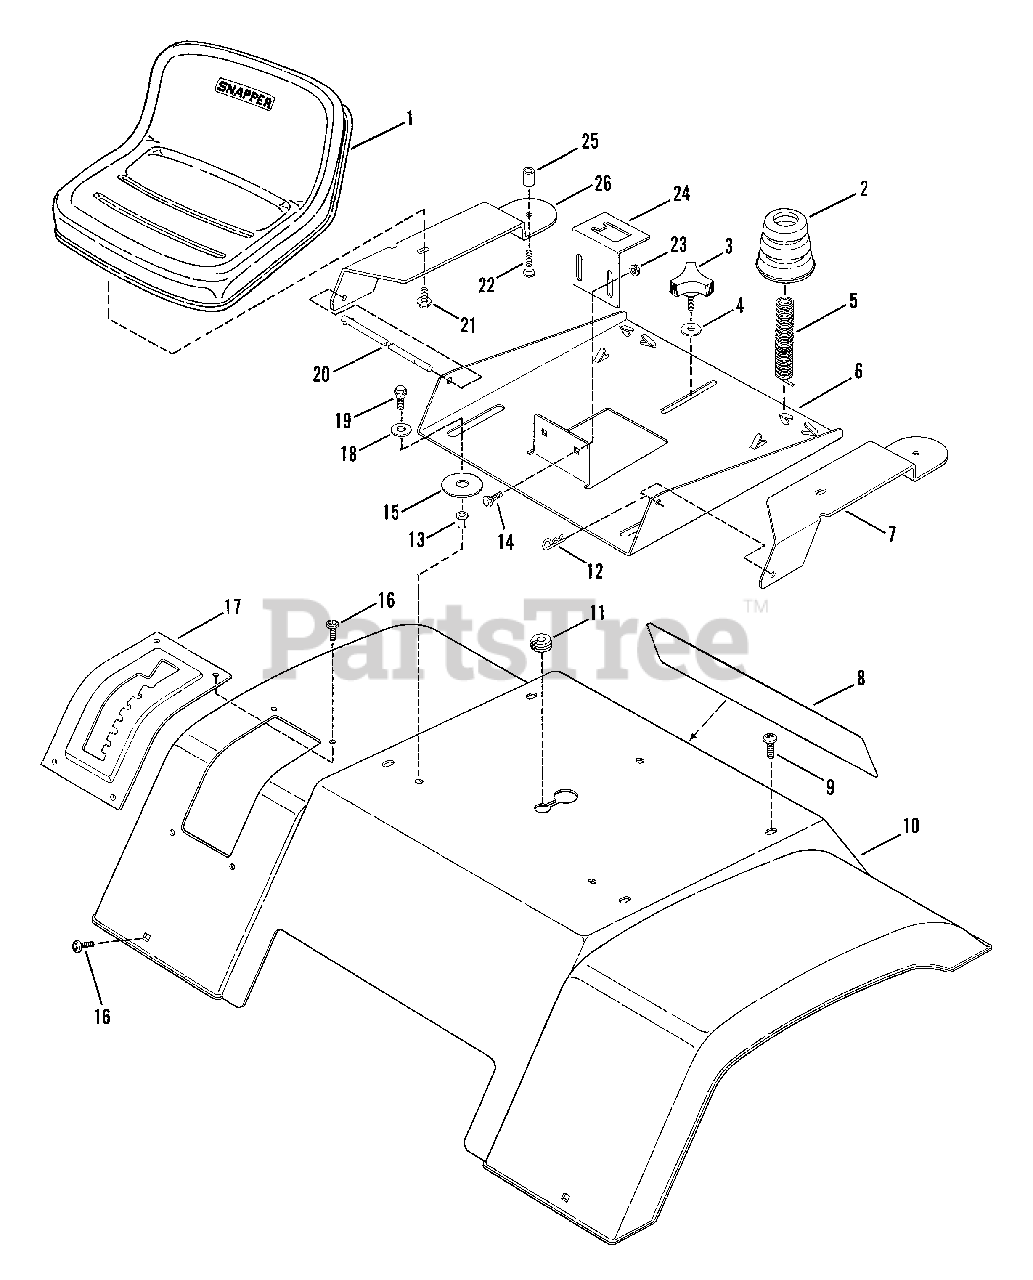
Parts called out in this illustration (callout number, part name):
1	SEAT, Operator's
2	CUSHION, Seat
3	KNOB, Seat Adjustment
4	WASHER
5	SPRING
6	SUPPORT, Seat
7	BRACKET, Seat Support, L.H.
8	DECAL, SNAPPER
9	SCREW, 5/16-18x7/8" Torx. Hd., S.T.
10	FENDER, Rear
11	GROMMET, 5/16 I.D.x1" O.D. Split
12	PIN, Hair
13	RIV-NUT, 5/16-18
14	BOLT, 5/16-18x5/8" Short Neck Carriage
15	SPACER
16	SCREW, 1/4-20x5/8" Torx Hd., Self-Tapping
17	DETENT, Shift
19	SCREW, Shoulder, 5/16-18x3/4"
20	ROD, Seat Hinge
21	BOLT, 5/16-18x1/2" Hex Flange Lock
22	SCREW, 5/16cx1" Flat Hd. Hex Recess
23	NUT, 5/16-18 Hex Flange Lock
24	BRACKET, Switch
25	SPACER,
26	BRACKET, Seat Support, R.H.
